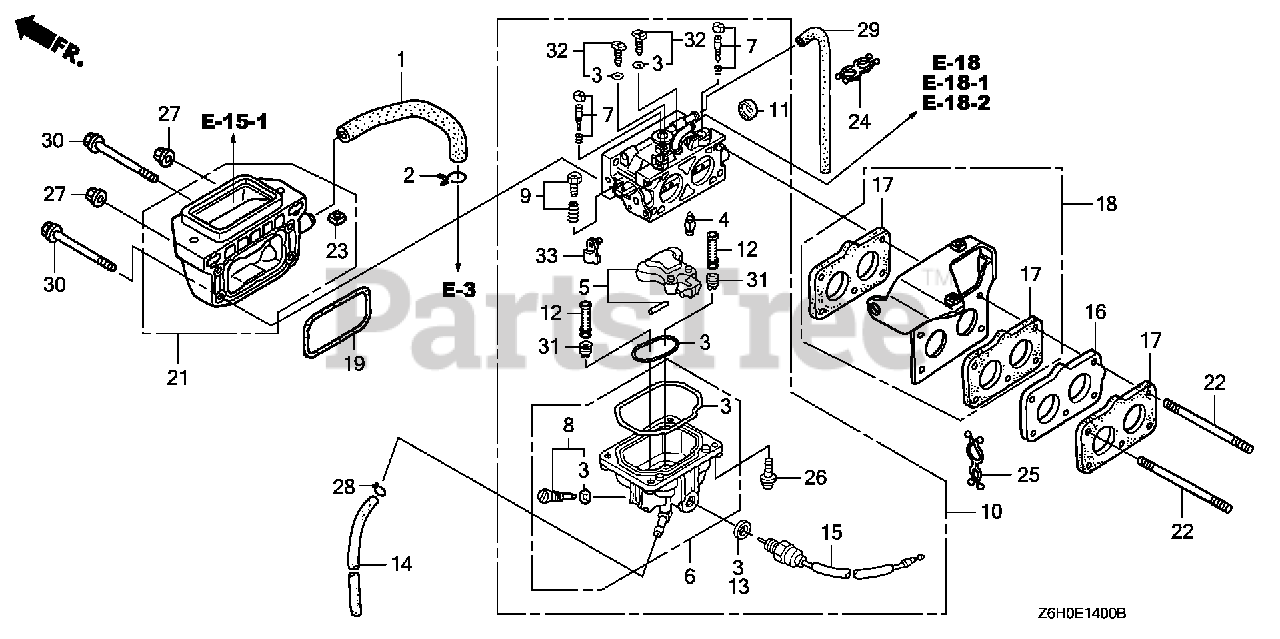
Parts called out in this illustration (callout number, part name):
1	TUBE, BREATHER
2	CLIP, BREATHER TUBE
3	GASKET SET
4	VALVE SET, FLOAT
6	CHAMBER SET, FLOAT
7	SCREW SET, PILOT
8	SCREW SET, DRAIN
9	SCREW SET, THROTTLE
10	CARBURETOR ASSY. (BK02C B)
11	CAP, CHOKE DUST
12	NOZZLE, MAIN (CARBURETOR NO.)
13	WASHER, PLAIN
14	TUBE, DRAIN
15	VALVE ASSY., SOLENOID (KEIHIN)
16	INSULATOR, CARBURETOR
17	GASKET, CARBURETOR
18	STAY, FUEL PUMP
19	GASKET, AIR CLEANER
21	ELBOW, AIR CLEANER
22	BOLT, STUD (6X113)
23	NUT, INSERT (6MM)
24	CLIP, WIRE HARNESS
25	CLIP, PURSE LOCK
26	SCREW, PAN (4X12)
27	NUT, FLANGE (6MM)
28	CLIP, TUBE (B8)
29	BULK HOSE, VACUUM (4.5X1000) (4.5X540)
30	BOLT, FLANGE (6X115)
31	JET, MAIN (#95) (CARBURETOR NO.)
31	JET, MAIN (#98) (CARBURETOR NO.)
31	JET, MAIN (#100) (CARBURETOR NO.)
32	JET SET, PILOT (#38) (CARBURETOR NO.)
33	ARM, THROTTLE LINKAGE
